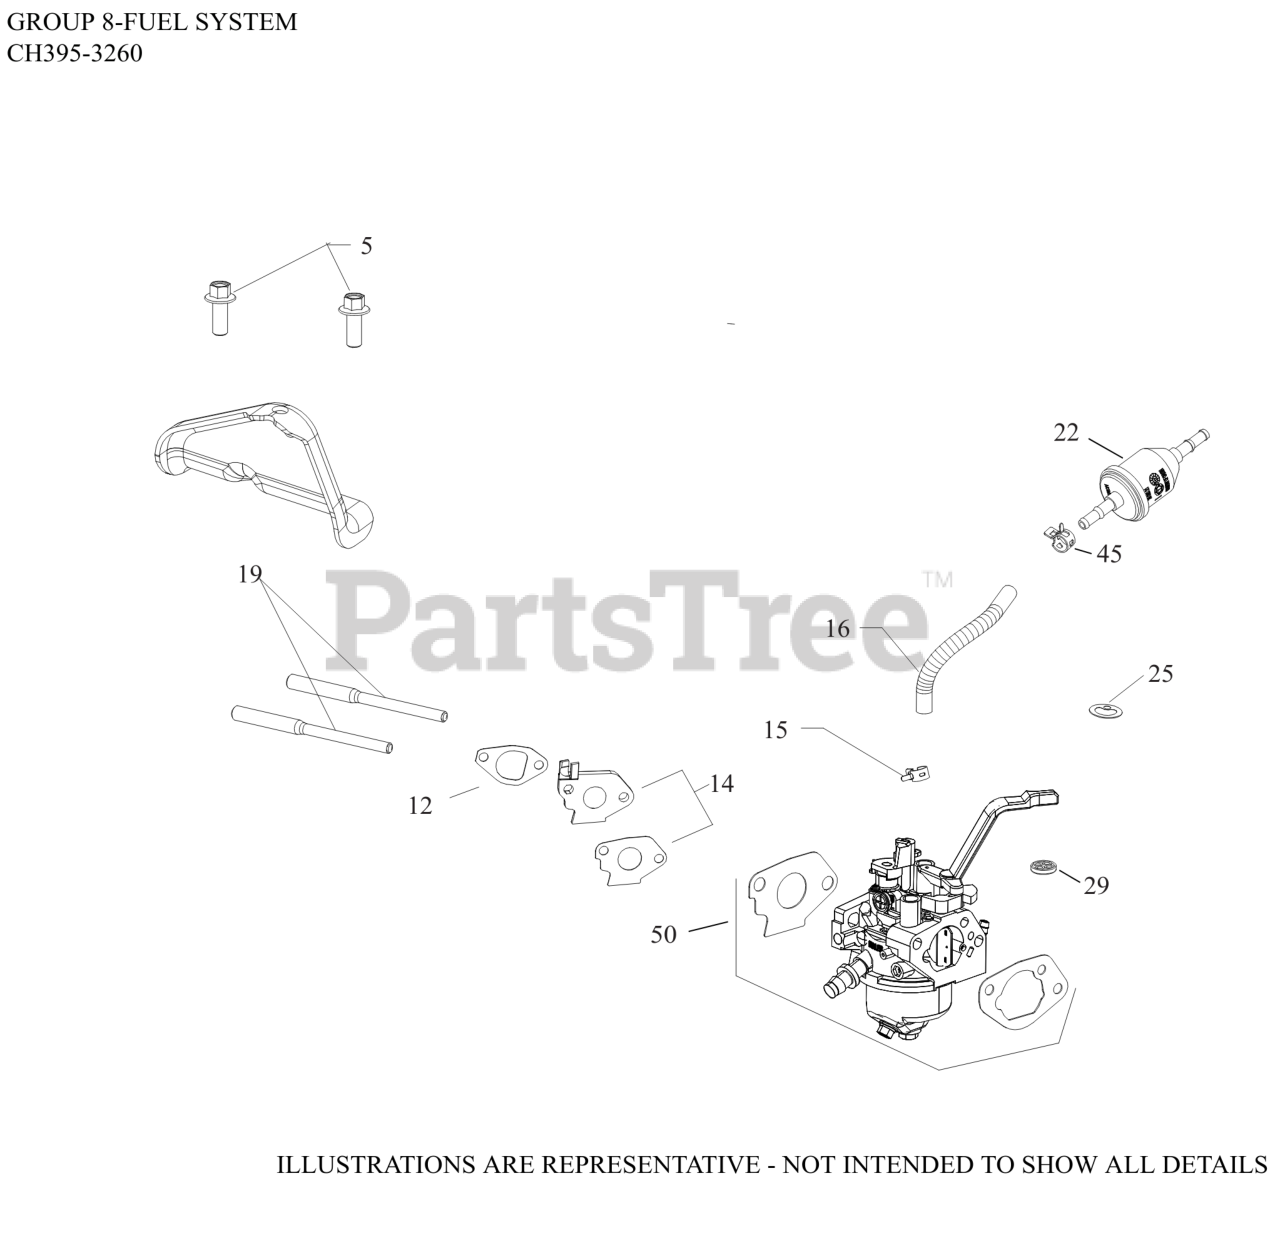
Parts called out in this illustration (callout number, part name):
5	SCREW, M8 X 20
12	KIT, INTAKE GASKETS
14	INSULATOR AND GASKET KIT
15	CLAMP, FUEL LINE
16	FUEL HOSE, LOW PERMEATION
19	STUD, INTAKE
22	FILTER,FUEL 75 MICRON (GRAVTY FEED)
25	KIT, FUEL SCREEN
29	SEAL, INLET VALVE
45	CLAMP, HOSE
50	KIT, CARBURETOR COMPLETE
NI	TOOL, SPARK PLUG WRENCH ASSY
NI	KIT, HIGH ALTITUDE (4,000-8,000 FT)
NI	KIT, HIGH ALTITUDE (ABOVE 8,000 FT.)
NI	KIT, CARBURETOR REPAIR
